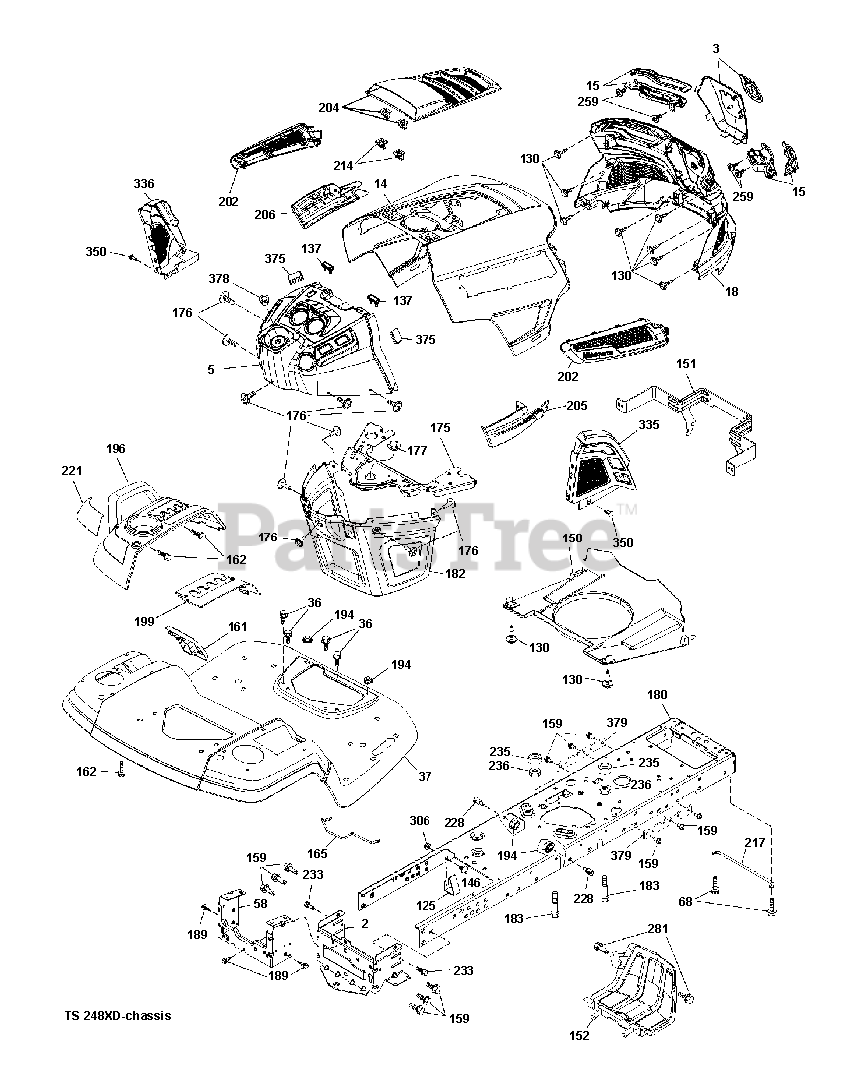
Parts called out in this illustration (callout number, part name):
2	DRAWBAR.LOWER.2PC.18/22
5	DASH.UPR.GT2.DUAL.RD.PT
14	KIT.HOOD.ASM.HUSQ.GT.TEX.668
15	Service Kit
36	BOLT.5/16-18UNCX3/4 W/SEMS.BLK
37	FENDER.PNT.TX.GT.CH/FW/DL.HUSQ
58	DRAWBAR.UPPER.2PC,LRG.FENDER
125	CLIP.FUEL.LINE
137	BUMPER DASH
146	BOLT.RDHD.SHT.SQNK.3/8-16X5/8
150	AIR.DUCT.GTV.BLACK
151	SERVICE KIT PIVOT BRACKET BRAC
152	SHIELD.BROWNING.PNT.GT.V2
159	SCREW, 3/8-16X3/4
161	CONSOLE.FUEL.WINDOW.HU
165	SUPPORT.TANK.REAR.B/TE
175	PLATE.PNT.CROSSMEMBER.HUSQ/PRE
176	SCREW.#10-24X5/8.RN.QU
177	BUSHING STEERING
180	KITS.TEX.BOLTED.CHASSIS.445559
182	DASH.LOWER.COMMON.12V.ADAPTOR
189	BOLT.HEX.HD.WASHER.5/16-18X.75
196	SUBASM.CONSOLE.HUSQ.GT.DECKLFT
199	PLATE.DECK.LIFT.HUSQVARNA.GT
202	Vents
205	SIDE.TRIM.RH.GT.HUSQ.II
206	SIDE.TRIM.LH.GT.HUSQ.II.GRAY
214	CLIP.RETAINER.TINNER.
217	ROD.PIVOT.HOOD
221	REFLECTOR.LH.TEX GT HU
228	STUD.W/"D"ANTI-ROTATION
233	BOLT.SHOULDER
236	NUT.CENTERLOCK.5/16-
281	SCREW 3/8-16X1
306	NUT.HEX.FLANGE.3/8-16.LOCKNUT
335	COVER.LOWER.DASH.RH.BLACK
336	COVER-LH.LOWER.DASH.GT2.BLACK
350	CLIP.X-MAS.TREE
375	BUMPER CLIP-ON. DASH 1"
378	BUSHING FLANGE; PLASTIC
379	CHASSIS.PLATE.REINFORCEMNT.431
